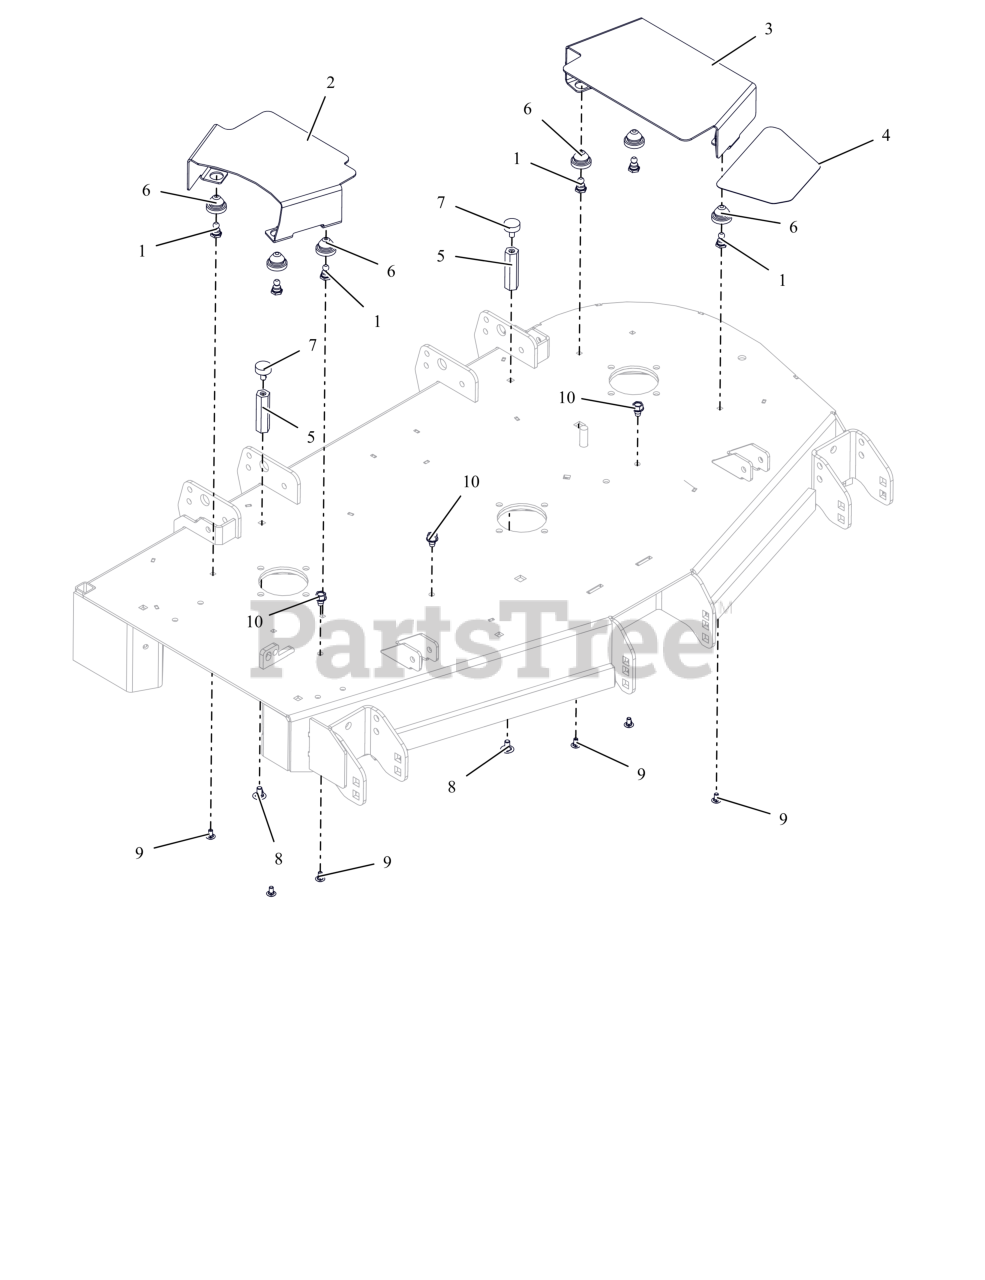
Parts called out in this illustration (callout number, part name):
1	BAFFLE, 60" RH VACUUM (RED)
2	BAFFLE, 60" LH VACUUM (RED)
3	WHEEL, ANTI SCALP - 5X3 CTR W/RIBS
4	BLT,RHSN .31-18X.75 G5 ZCC
5	BTL,RHSN .500-13 X 8.5S G5 ZCC
6	BLT, RHSN .50-13X5.00 G5 ZCC
7	NUT,NYL-FLG .50-13 GF ZCC
8	NUT,NYL .31-18 G5 ZCC
